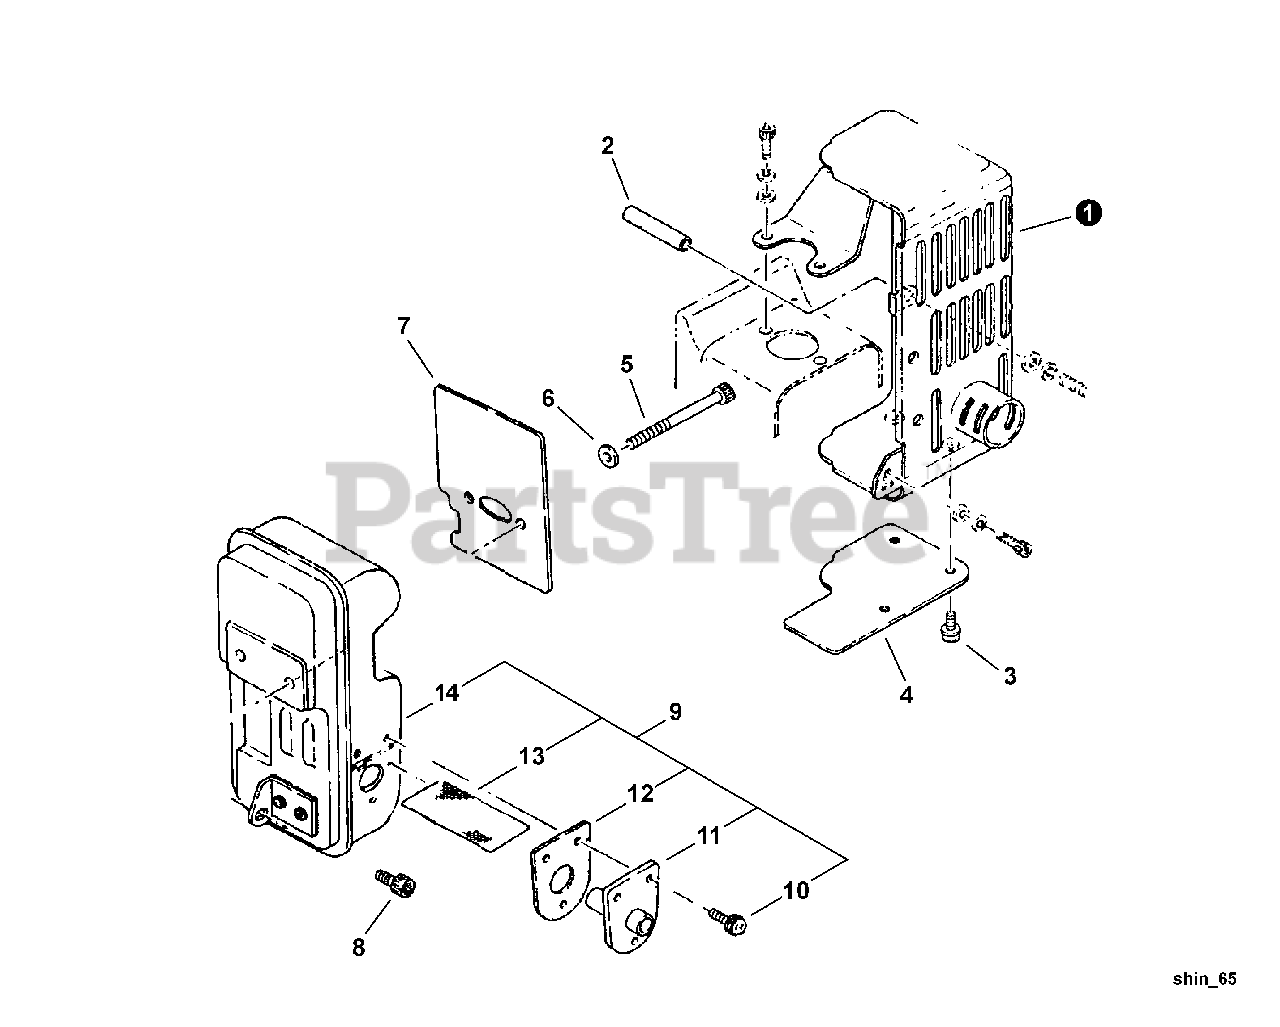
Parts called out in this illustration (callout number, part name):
1	COVER, EXHAUST
2	SPACER
3	SCREW M4×8
4	GASKET, GUARD
5	BOLT
6	WASHER 6.5×11.5×0.8
7	GASKET, EXHAUST
8	BOLT M5×12
9	MUFFLER ASSY
10	SCREW M4×12
11	GUIDE, EXHAUST
12	GASKET, EXHAUST
13	SCREEN, SPARK ARRESTER
14	MUFFLER
